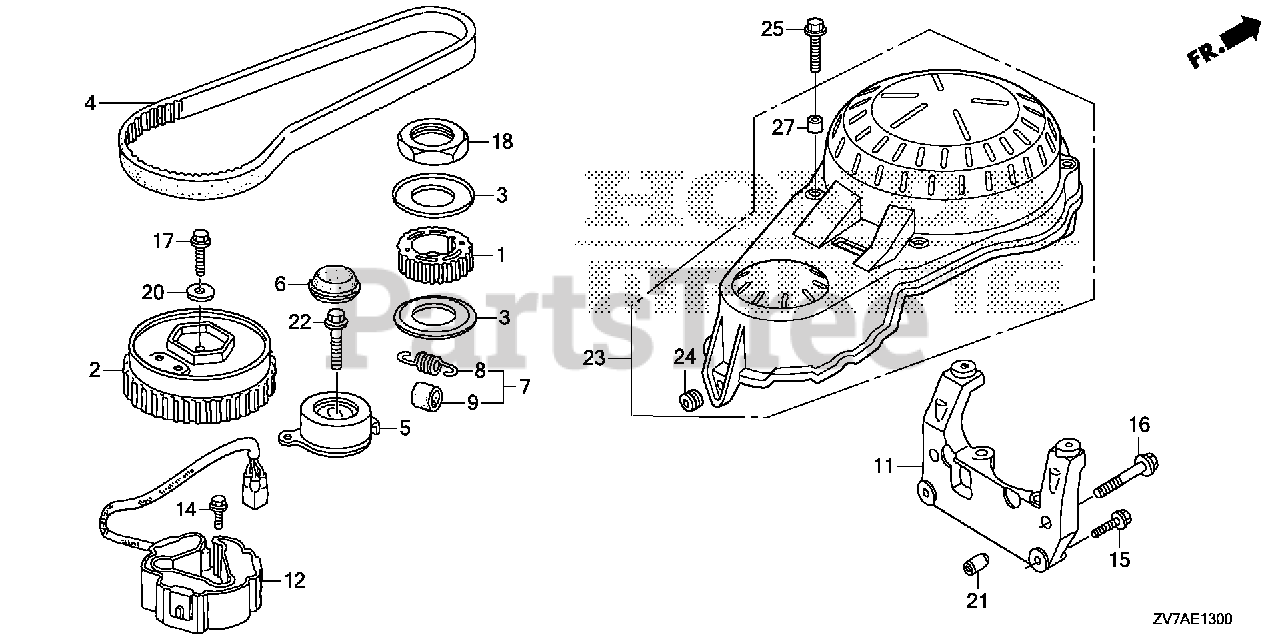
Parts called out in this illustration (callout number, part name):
1	PULLEY, TIMING
2	PULLEY, CAMSHAFT
3	PLATE, TIMING BELT GUIDE
4	BELT, TIMING
5	TENSIONER, TIMING BELT
6	CAP, TIMING BELT TENSIONER
7	SPRING, TIMING BELT ADJUSTING
8	SPRING, TIMING BELT ADJUSTING
9	BOOT, SPRING
11	BRACKET, RECOIL
12	COIL ASSY., PULSER
14	BOLT, FLANGE (6X12) (CT200)
15	BOLT, FLANGE (6X22)
16	BOLT, FLANGE (8X45)
17	BOLT, FLANGE (8X25)
18	NUT, LOCK (34MM)
20	WASHER, PLAIN (8MM)
21	PIN, DOWEL (10X16)
22	BOLT, FLANGE (10X38)
23	COVER, FLYWHEEL
24	GROMMET, SIDE COVER
25	BOLT, FLANGE (6X22)
27	COLLAR (6.5X11X10)
